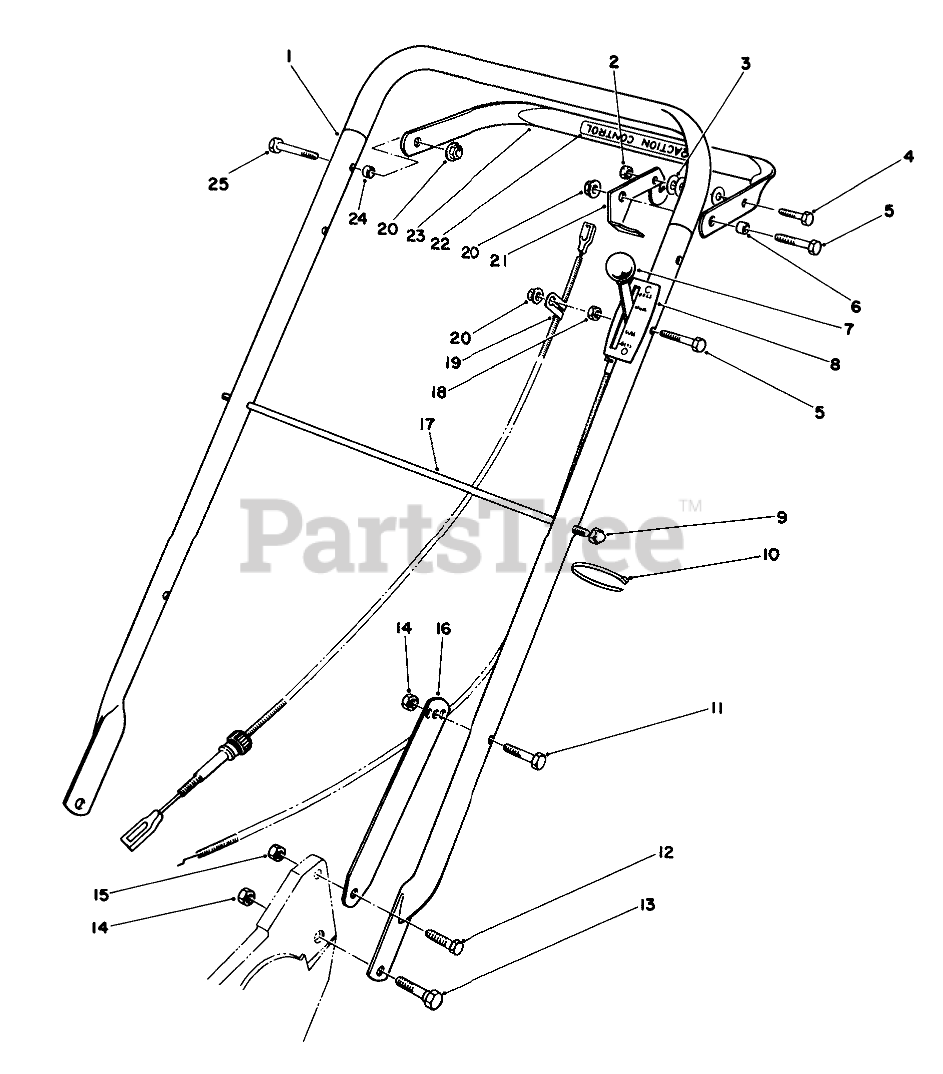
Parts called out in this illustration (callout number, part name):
1	Handle
2	NUT-LOCK, NI
3	WASHER-FLAT
4	SCREW-HH
5	SCREW-HH
6	Standoff-Lift Bail
7	KNOB-CONTROL
8	Control-Throttle (Incl. Ref. #7) Bend Type #1 Sheath Lg. 63.5 Inch. Wire Lg. 2.5 Inch.
9	NUT-CAP
10	TIE-CABLE
11	SCREW-HH
12	SCREW-HH
13	SCREW-SHOULDER
14	NUT-LOCK, CONE
15	NUT-LOCK, NI
16	Latch-Handle
17	ROD-SUPPORT, BAG
18	NUT-JAM
19	TRACTION CABLE
20	NUT-LOCK, HHF
21	Lever-Control
22	TRACTION DECAL
23	Lift Bail
24	STANDOFF LIFT BAIL
25	SCREW-HH
